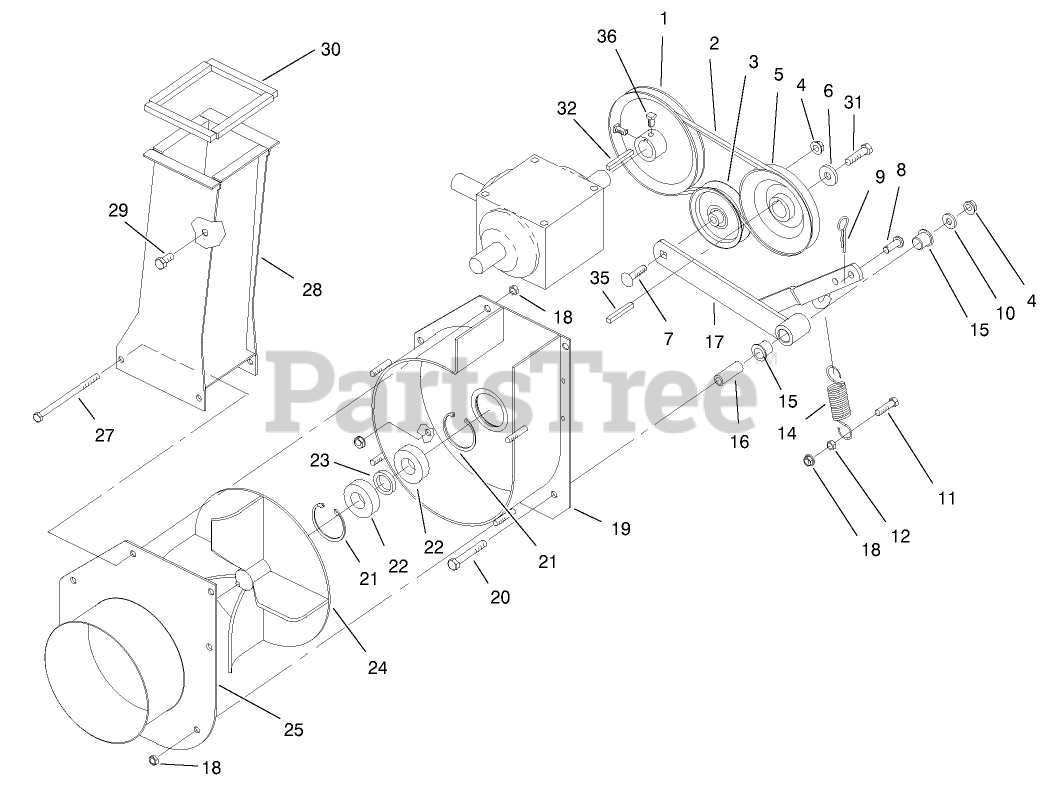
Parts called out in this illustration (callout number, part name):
1	PULLEY-GEARBOX
2	V-BELT
3	PULLEY-IDLER
4	NUT-HF
5	PULLEY - IMPELLER B
6	WASHER-THRUST, PLAIN
7	SCREW-CARR
8	PIN-CLEVIS
9	PIN-HAIR
10	WASHER-FLAT
11	SCREW-HH
12	NUT-HEX
14	SPRING-EXTENSION
15	BUSHING-FLANGE
16	SPACER
17	Idler Arm
18	NUT-HF
19	Housing
20	SCREW-HH
21	RING-SNAP
22	BEARING-BALL
23	SPACER-BEARING
24	Impeller ASM
25	Cover
27	SCREW-HH
28	Impeller Chute
29	SCREW-HH
30	STRIP - FOAM
31	SCREW-HH
32	KEY-SQUARE
35	KEY-SQUARE
36	SCREW-SET, SQH
